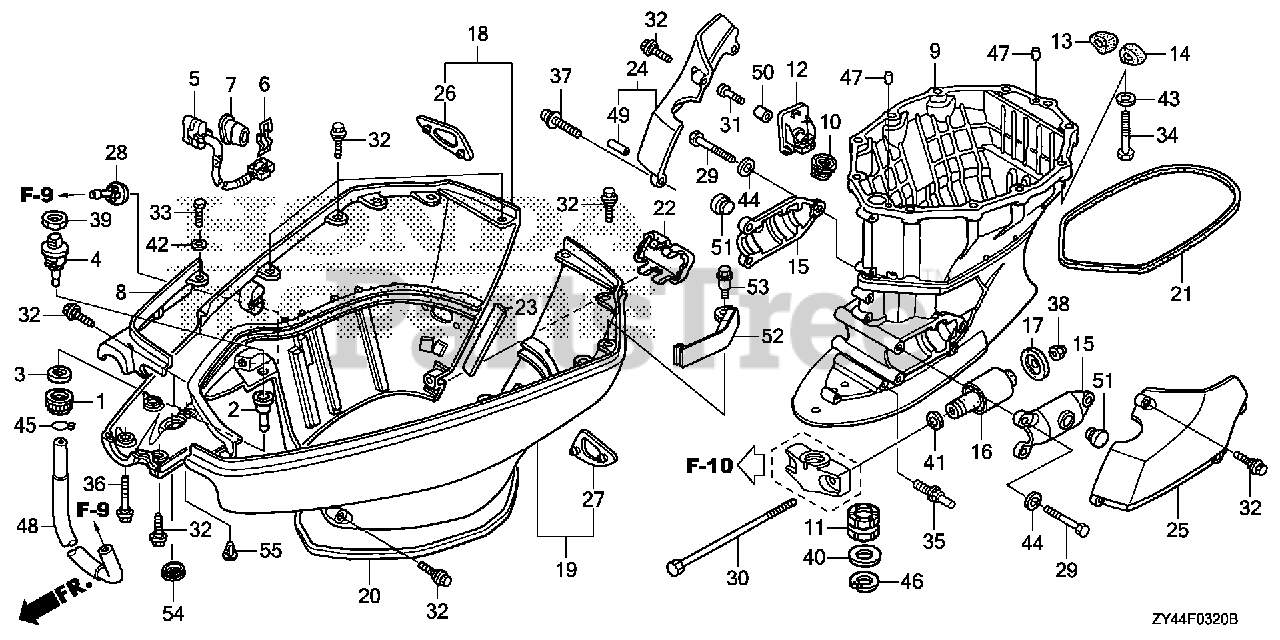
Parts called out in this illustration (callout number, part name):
1	NUT, WATER MOUTH
2	JOINT, WATER HOSE
3	SEAT, WATER MOUTH
4	CAP, WATER JOINT
5	SWITCH ASSY., POWER TILT
6	STAY, POWER TILT SWITCH
7	GROMMET, POWER TILT SWITCH
8	COVER, FR. SEPARATE *NH282MU* (OYSTER SILVER METALLIC-U)
9	CASE, EXTENSION *NH282MU* (L) (OYSTER SILVER METALLIC-U)
10	RUBBER, DRAIN PLUG
12	COVER, DRAIN PLUG *NH282MU* (L) (OYSTER SILVER METALLIC-U)
13	SEAL, R. IDOL PORT
14	SEAL, L. IDOL PORT
15	HOUSING, MOUNTING (LOWER)
16	MOUNT, RUBBER (LOWER)
17	STOPPER, MOUNT (LOWER)
18	COVER, R. ENGINE (LOWER) *NH282MU* (OYSTER SILVER METALLIC-U)
19	COVER, L. ENGINE (LOWER) *NH282MU* (OYSTER SILVER METALLIC-U)
20	SEAL A, COVER (LOWER)
21	SEAL B, COVER (LOWER)
22	CAP, COVER (LOWER) *NH282MU* (OYSTER SILVER METALLIC-U)
23	SEAL C, COVER (LOWER)
24	COVER, R. MOUNTING (LOWER) *NH282MU* (L) (OYSTER SILVER METALLIC-U)
25	COVER, L. MOUNTING (LOWER) *NH282MU* (L) (OYSTER SILVER METALLIC-U)
26	GROMMET, R. IDLE PORT
27	GROMMET, L. IDLE PORT
28	GROMMET, WATER CHECK
29	BOLT, HEX. (10X35)
30	BOLT, HEX. (14X180)
31	SCREW, SPECIAL (6X35)
32	BOLT, SPECIAL (6X17)
33	BOLT, HEX. (6X25)
34	BOLT, HEX. (12X50)
35	BOLT, SPECIAL (6X12)
36	BOLT, SPECIAL (6X37)
37	SCREW-WASHER (6X40)
38	NUT, SELF-LOCK (14MM)
39	NUT, HEX. (16MM)
41	WASHER, PLAIN (14MM)
42	WASHER (6MM)
43	WASHER, PLAIN (12MM)
44	WASHER, PLAIN (10MM)
45	CLIP, TUBE (B12.5)
47	PIN, DOWEL (6X10)
48	TUBE, WATER JOINT
49	COLLAR (6.2X10X25.5)
50	COLLAR, DISTANCE (6X10.5X25)
51	RUBBER C, STAND STOPPER
52	COVER, PLUG MAINTENANCE
53	BOLT, SPECIAL (6X22)
54	GROMMET, CASE (LOWER) (C)
55	PLUG, HOLE (5MM)
